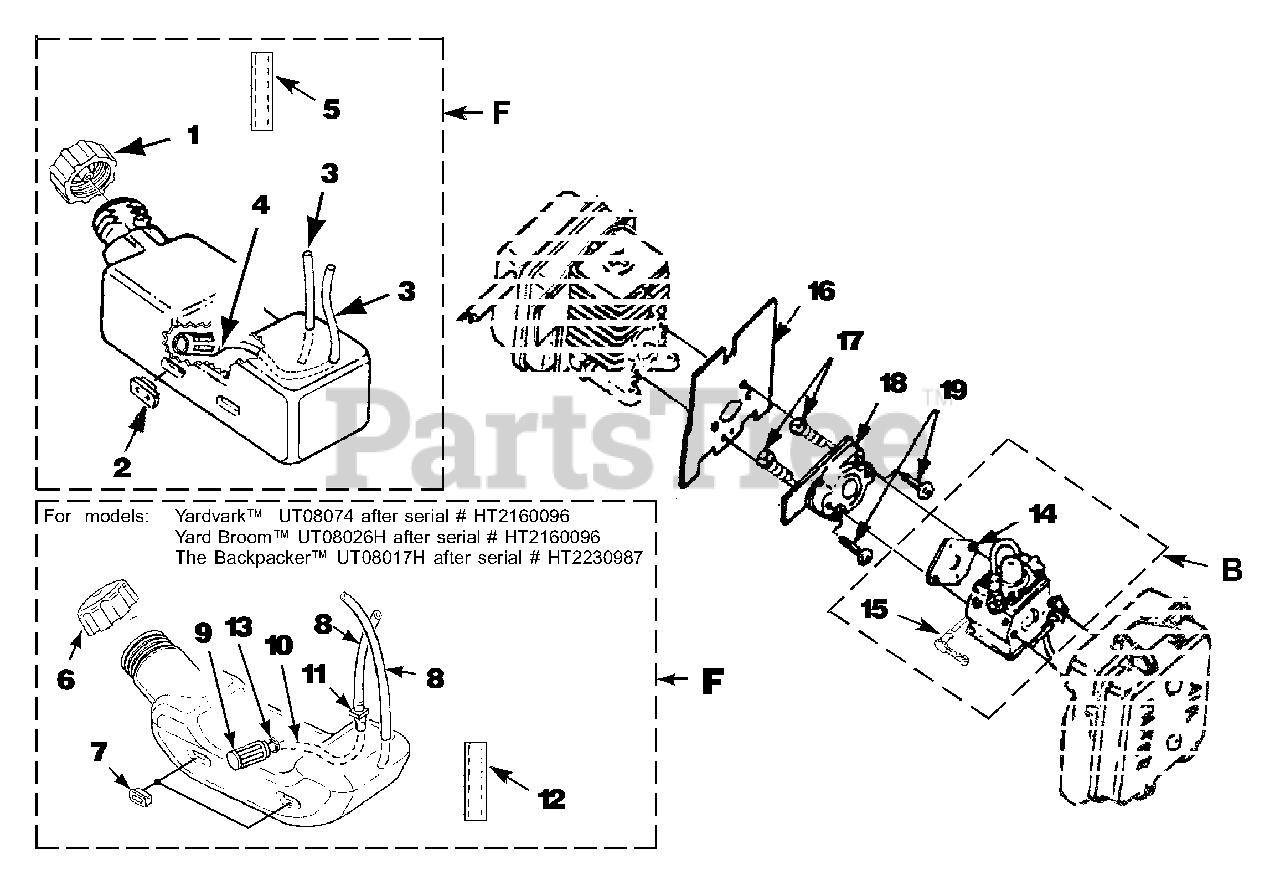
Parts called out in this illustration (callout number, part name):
1	FUEL CAP (1 3/8" Opening)
2	BUMPER-Rubber
3	TUBING-Rubber (8")
4	FUEL FILTER
5	INSULATION-Tubing
6	FUEL CAP (1 5/8" Opening)
7	BUMPER-Rubber
8	TUBING-Rubber (8")
9	FUEL FILTER
10	TUBING-Rubber (8")
11	Fitting, Inlet (small for 2.5mm ID fuel line)
12	INSULATION-Tubing
13	CLAMP
14	GASKET-Carburetor
14	(GASKET-Carburetor)
15	LEVER-Choke
16	GASKET-Heat Dam
17	SCREW-Thread Form. (10-24 x 1")
18	HEAT DAM
19	SCREW, SEMS (10-24 x 1.110)
F	FUEL TANK KIT
B	CARBURETOR KIT
